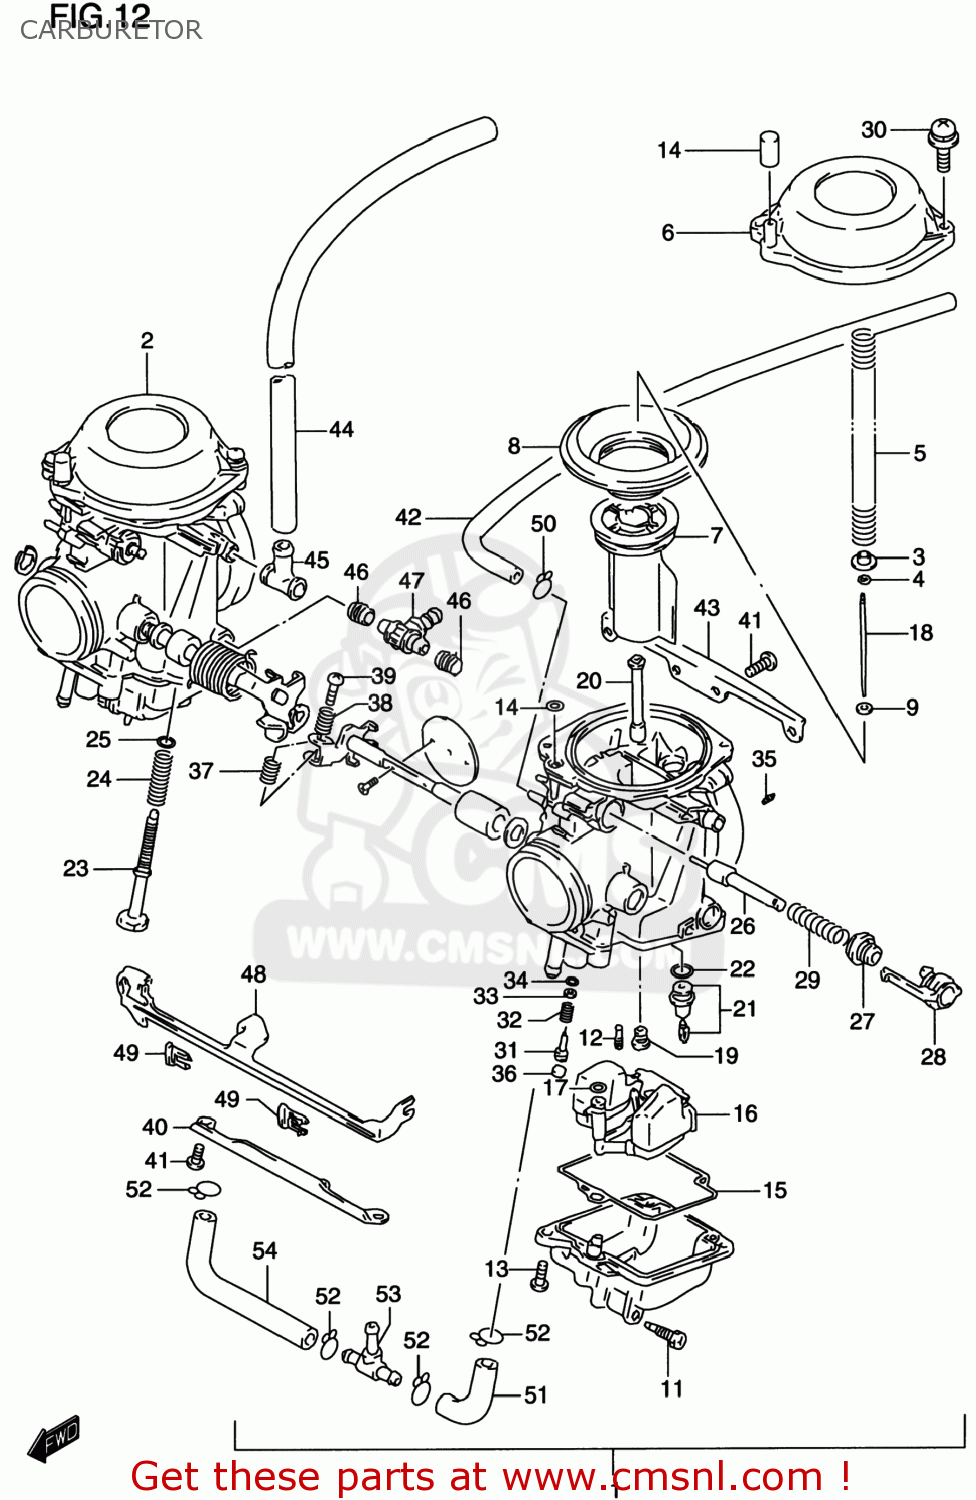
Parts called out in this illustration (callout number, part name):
1	CARBURETOR ASSEMBLY,LEFT
2	CARBURETOR ASSY,R
3	RING
4	E RING
5	SPRING
6	COVER,DIAPHRAGM
7	VALVE,PISTON
8	DIAPHRAGM
9	RING
10	CAP
11	SCREW,DRAIN
12	JET,PILOT(37.5)
13	SCREW
14	O RING
15	GASKET,FLOAT CHAMBER (NAS)
16	FLOAT ASSY
17	O RING
18	NEEDLE,JET
19	JET,MAIN(122.5)
20	JET,NEEDLE(O-3M)
21	VALVE ASSY,NEEDLE
22	O-RING,NEEDLE VALVE
23	SCREW,ADJUSTER
24	SPRING
25	WASHER
26	PLUNGER ASSY
27	CAP,STARTER
28	HOLDER,GUIDE
29	SPRING
30	SCREW
31	SCREW,PILOT
32	SPRING
33	WASHER
34	O RING,PILOT AIR SCREW
35	JET,AIR(1.3)
36	PLUG
37	SPRING,THROTTLE SCREW
38	SPRING
39	SCREW
40	PLATE
41	SCREW
42	HOSE(5X9X350)
43	PLATE
44	HOSE(7X11X600)
45	HOSE
46	SEAL
47	NIPPLE
48	LEVER
49	HOLDER
50	CLIP
51	HOSE
52	CLIP
53	NIPPLE
54	HOSE
